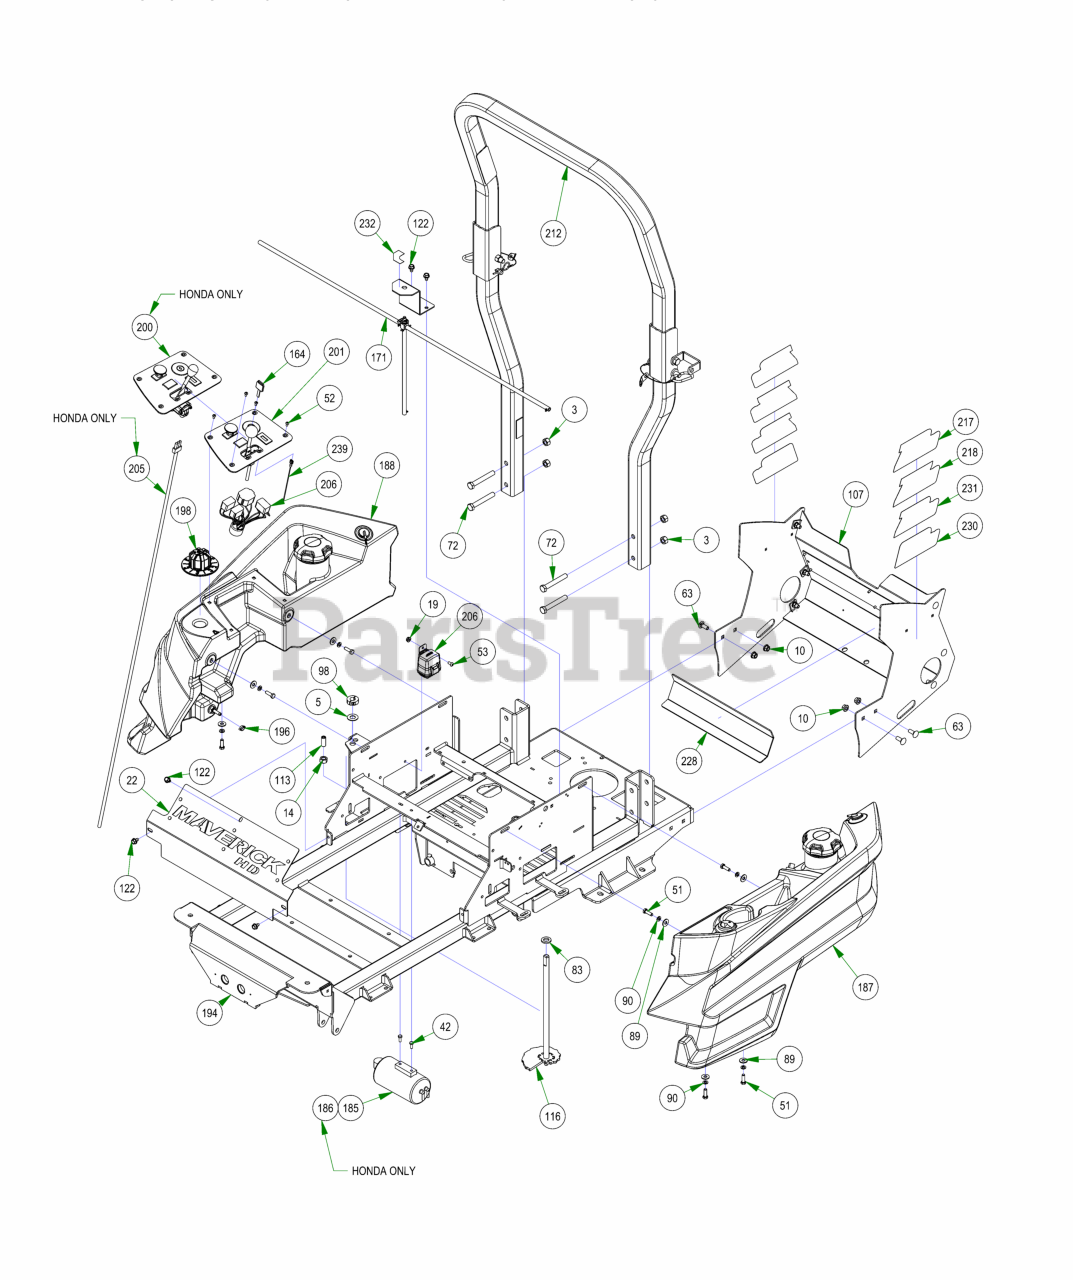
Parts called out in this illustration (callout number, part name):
3	1/2-13 HEX 2-WAY REVERSIBLE CENTER LOCKNUT Grade B ZINC
5	.625 ID x 1.250 OD x .062 THK F/W Nylon
10	3/8-16 NYLON INSERT FLANGE LOCKNUT (GR.F) ZINC
14	1/2-13 HEX NUT ZINC
19	1/4-20 HEX SERRATED FLANGE NUT HARD/ZINC
22	Maverick HD Cooler Cover
42	M6-1.0 X 16MM DIN 933 HEX TAP BOLT (CL 8.8) ZINC
51	5/16-18 X 1 HEX CAP SCREW (GR.5) ZINC
52	10-32 X 3/8 BUTTON SOCKET CAP SCREW 18-8 STAINLESS
53	1/4-20 X 1/2 BUTTON SOCKET CAP SCREW 18-8 STAINLESS
63	3/8-16 X 1 CARRIAGE BOLT (GR.5) ZINC
72	1/2-13 X 3-1/2 HEX CAP SCREW (GR.5) ZINC
83	.635 ID X 1.120 OD X .140 THICK FLAT WASHER NYLON
89	5/16 USS FLAT WASHER (7/8 OD) ZINC
90	5/16 SPLIT LOCKWASHER ZINC
98	5/8" Split Collar
107	2022 Maverick Rear Cover Assembly
109	Fuel Shut Off Mounting Plate
113	Dial Rod Plunger
116	ZT Deck Height Bar Assembly
122	5/16-18 X 1/2 HWH unslot (F) tcs zinc
164	Ignition Key
171	2023 Maverick HD Fuel Line with Shutoff
185	2023 HD Kohler/Kawasaki EPA Canister Assembly
186	2023 Maverick HD Honda EPA Canister Assembly
187	2021 Maverick Left Side Tank
188	2022 Maverick HD RH Fuel Tank
194	2023 Maverick Frame - Painted
196	2 EAR CLAMP 12.5mm-15mm
198	MZ/ZT Deck Height Dial
200	2022 Maverick HD Honda Control Panel Assembly
201	2023 Control Panel Assembly
205	Honda E-Throttle Adapter
206	Wiring Harness
212	2016 2x2 ROPS
217	2022 Maverick 726cc Backplate Cluster
218	MAV HD/kohler bkplt decal
228	Heat Shield (Fiberglass Adhesive)
230	Honda Maverick HD 688cc Series Backplate Cluster
231	MavHD Honda 779cc Back Plate Decal
232	Maverick HD Shut Off Valve Decal
239	2017 MZ/ZT/MAV Tach Wire Assy
